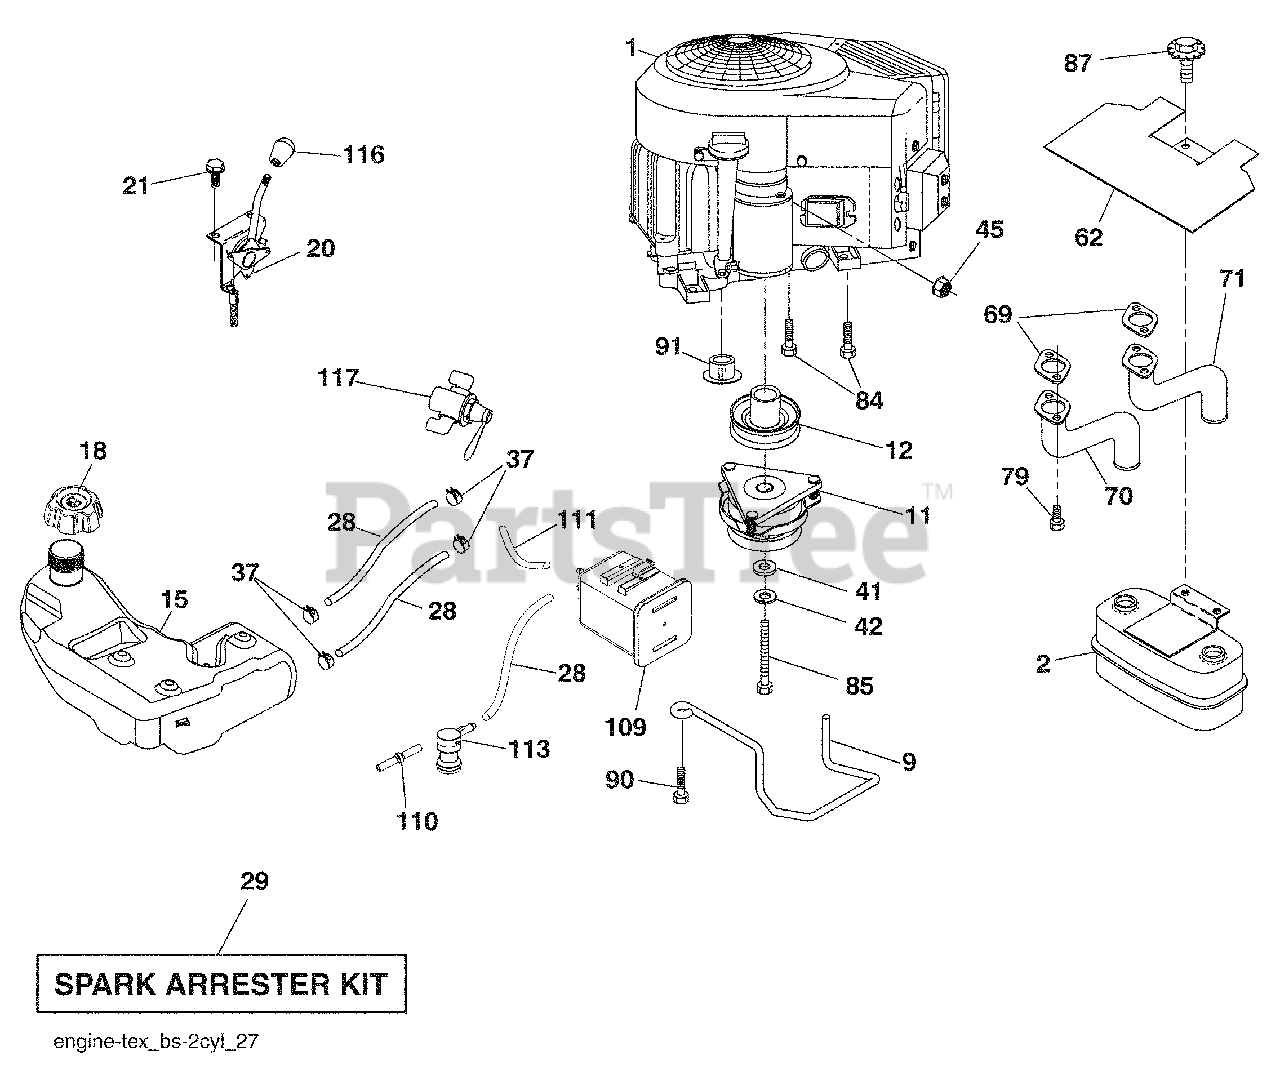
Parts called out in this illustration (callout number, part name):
9	Keeper Belt Engine
12	Pulley Engine
15	Tank Fuel
18	Cap Asm
20	Control Throttle
21	Screw #10 x .750 BOS Thread
28	Fuel Line
29	Spark Arrester Kit
37	Clamp Hose
41	Washer 1-1/2 OD x 15/32 ID x .250
42	Washer Lock 7/16
45	Nut Keps Hex 1/4-20 unc
62	Heat Shield
70	Tube Exhaust LH
71	Exhaust Tube RH
79	Screw Socket HD 5/16-18 x 1
84	Screw 3/8-16 x 1-1/4
85	Bolt 7/16-20 x 3.75 Gr. 5
87	Bolt 5/16-18 x 1
90	Screw 3/8-16 x 1
109	Canister Carbon Filter
110	Valve Anti-Slosh
111	Purge Line Carb.
113	Valve
116	Knob Soft Touch
117	Valve Fuel Reserve
